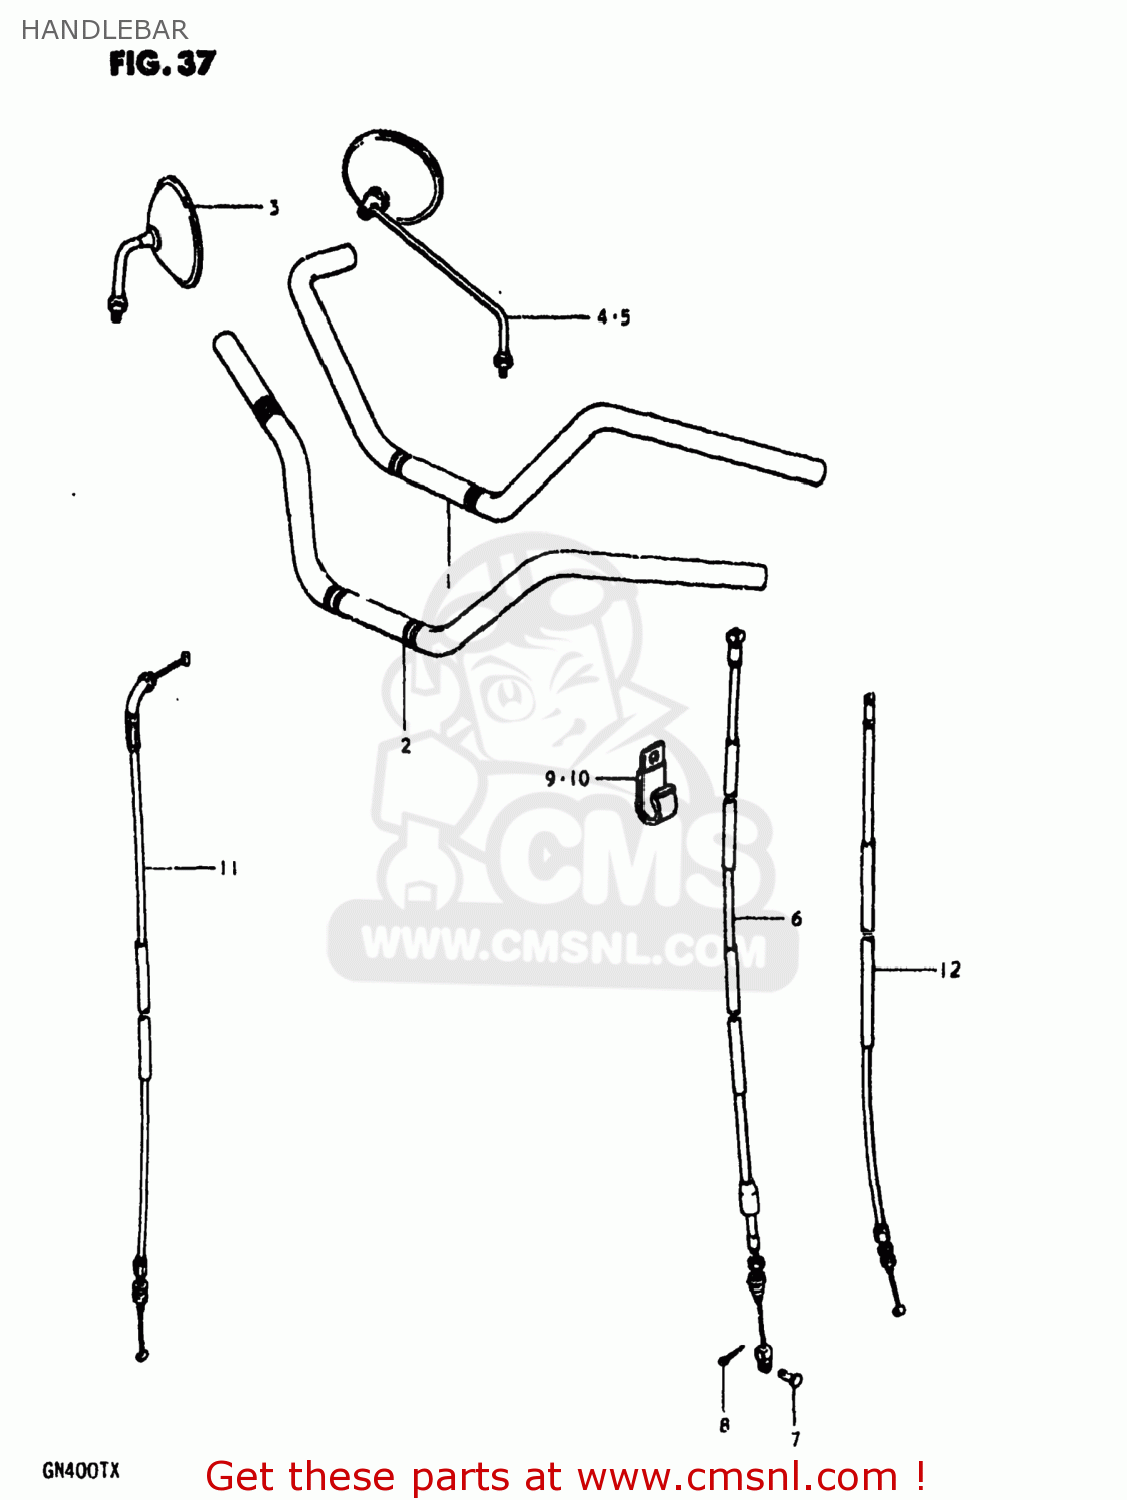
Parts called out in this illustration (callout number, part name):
1	HANDLEBAR
2	HANDLEBAR
3	MIRROR ASSEMBLY,RIGHT
4	MIRROR ASSEMBLY,RIGHT
5	MIRROR ASSEMBLY,LEFT
6	CABLE,CLUTCH
7	PIN(L:15)
8	PIN
9	CLAMP
10	CLAMP
11	CABLE ASSEMBLY,THROTTLE
12	CABLE,DECOMP
